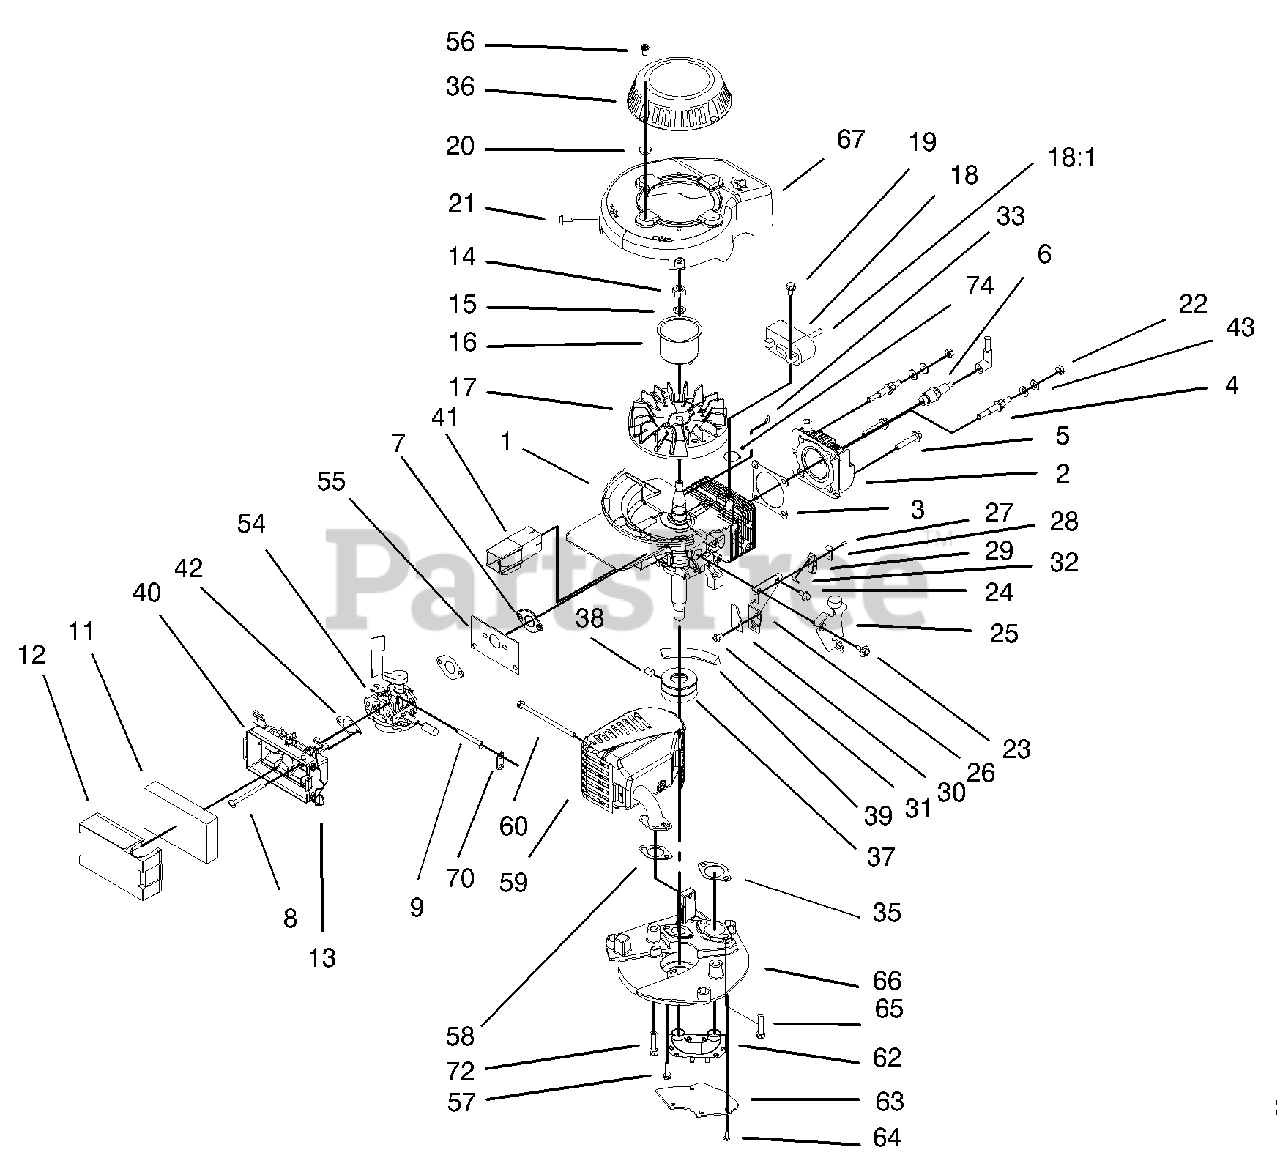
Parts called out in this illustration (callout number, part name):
1	SHORT BLOCK ASM
2	HEAD-CYLINDER
3	GASKET-HEAD
5	SCREW-HWH
6	SPARK PLUG
7	GASKET-INTAKE
9	HOSE-PRIMER
11	FILTER-AIR
12	COVER-FILTER, AIR
13	RETAINER-COVER, FILTER
15	WASHER-LOCK
16	HUB-STARTER E COMM.
17	FLYWHEEL
18	MODULE-IGNITION CD
18:1	Clip-High Tension Lead
20	SPACER E
21	SCREW-HH
23	SCREW-SHOULDER
24	SCREW-HWH
25	BRAKE PLATE AY EV
26	PLATE-BRAKE
27	RIVET-PLASTIC
28	STRAP-INSULATION
29	STRAP-GROUND
30	STOP-STRAP, GROUND
32	LEAD WIRE-SWITCH, BRAKE
35	GASKET-EXHAUST
36	ASM-Starter
38	SCREW-SET
39	V-BELT E
40	AIR BASE ASM
41	TUNNEL-INLET
42	GASKET-FILTER
43	WASHER-BELLEVILLE
54	CARBURETOR ASM
55	SHIELD-CARB E
59	MUFFLER & GUARD AY E
60	BOLT-CONSOLE
62	PIPE-TRANSFER
63	COVER-MUFFLER E
64	SCREW-HH
65	SCREW-HH
66	PLATE-MOUNTING
67	ASSEMBLY - SHROUD
70	HOSE-RETAINER
74	STRAP-TIE
